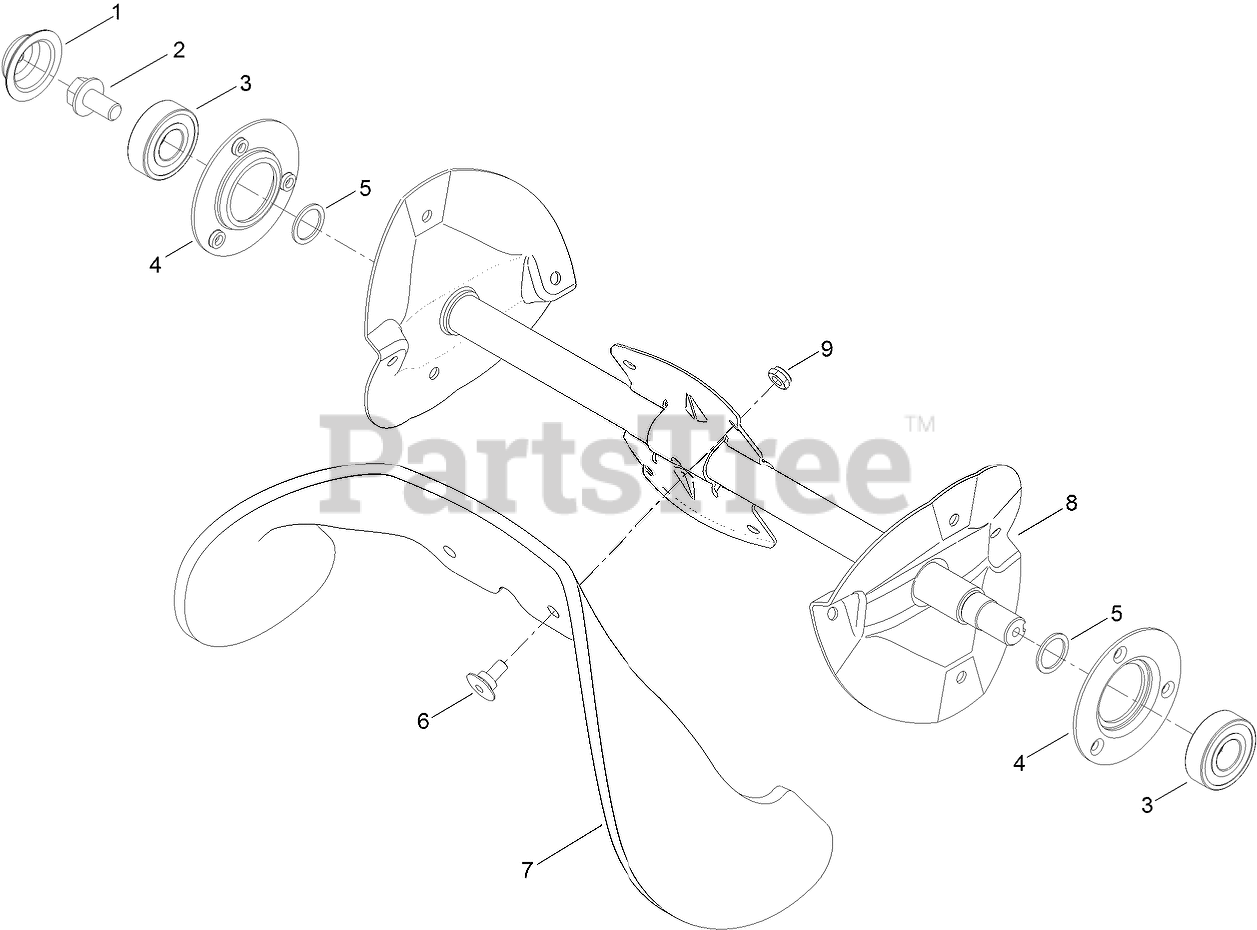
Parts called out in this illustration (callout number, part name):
1	CAP-SIDEPLATE, RH
2	SCREW-HWH
3	BEARING-BALL
4	FLANGE-BEARING
5	WASHER-THRUST
6	SCREW
7	BLADE-ROTOR
8	ROTOR ASM
9	NUT-LOCK, NI
